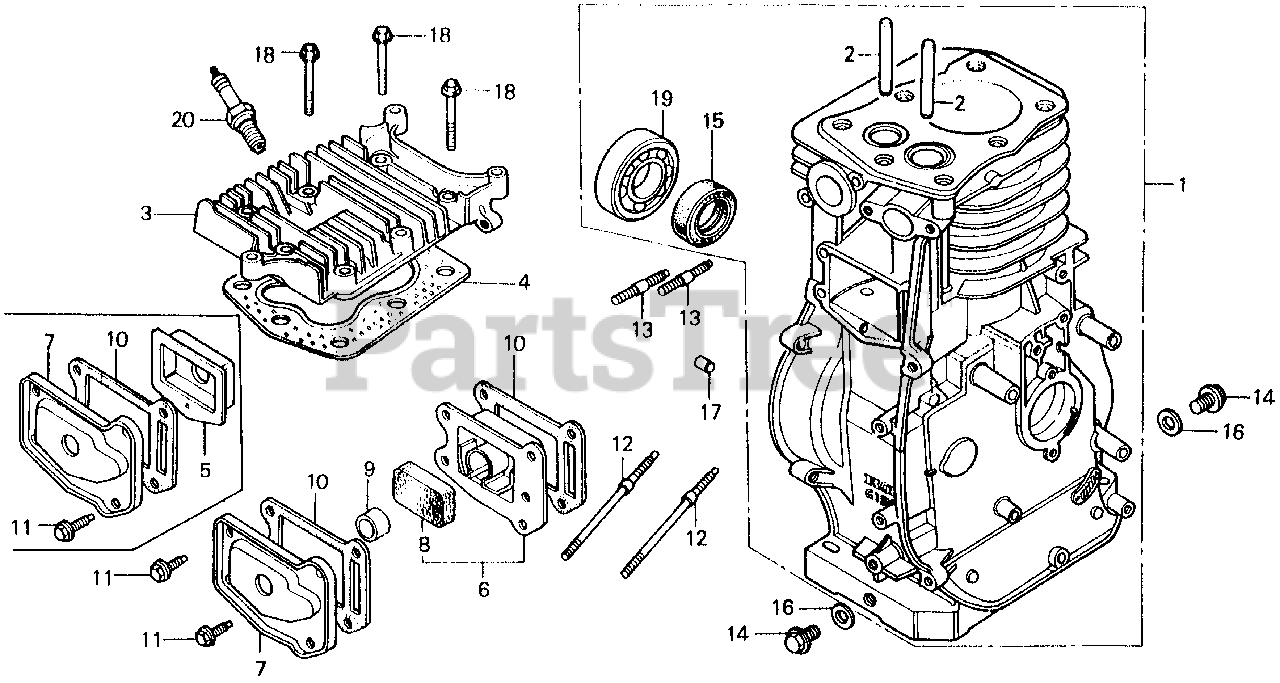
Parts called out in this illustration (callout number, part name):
1	CYLINDER ASSY.
2	GUIDE, VALVE (OS)
3	CYLINDER HEAD
4	GASKET, CYLINDER HEAD
5	CASE, BREATHER
6	CASE, BREATHER
7	COVER, TAPPET ROOM
8	FILTER, BREATHER
9	SEAL, BREATHER
10	GASKET, TAPPET COVER
11	BOLT, FLANGE (6X12) (CT200)
12	BOLT, STUD (6X96)
12	BOLT, STUD (6X89)
13	BOLT, STUD (8X35)
14	BOLT, DRAIN PLUG
15	OIL SEAL (25X41X6)
16	WASHER, DRAIN PLUG (12MM)
17	PIN A, DOWEL (8X14)
18	BOLT, FLANGE (8X45)
19	BEARING, RADIAL BALL (6205)
20	SPARK PLUG (BR-4HS) (NGK)
20	SPARK PLUG (W14FR-U) (DENSO)
